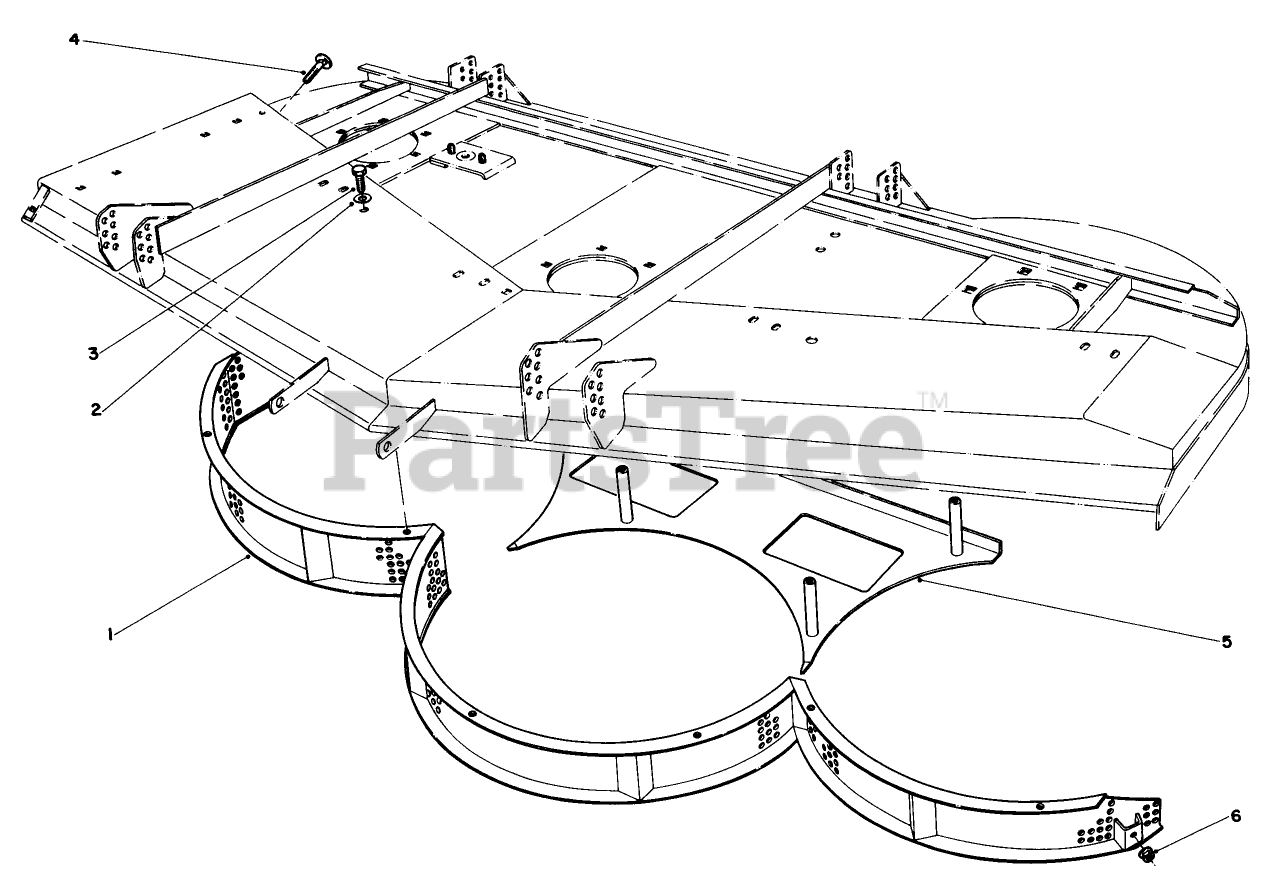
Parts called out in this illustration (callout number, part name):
1	Mulcher Screen
2	WASHER-LOCK
3	SCREW-HH
4	BOLT-CARR
5	Shelf-Bottom Rear
6	NUT-HHF, WHIZ
